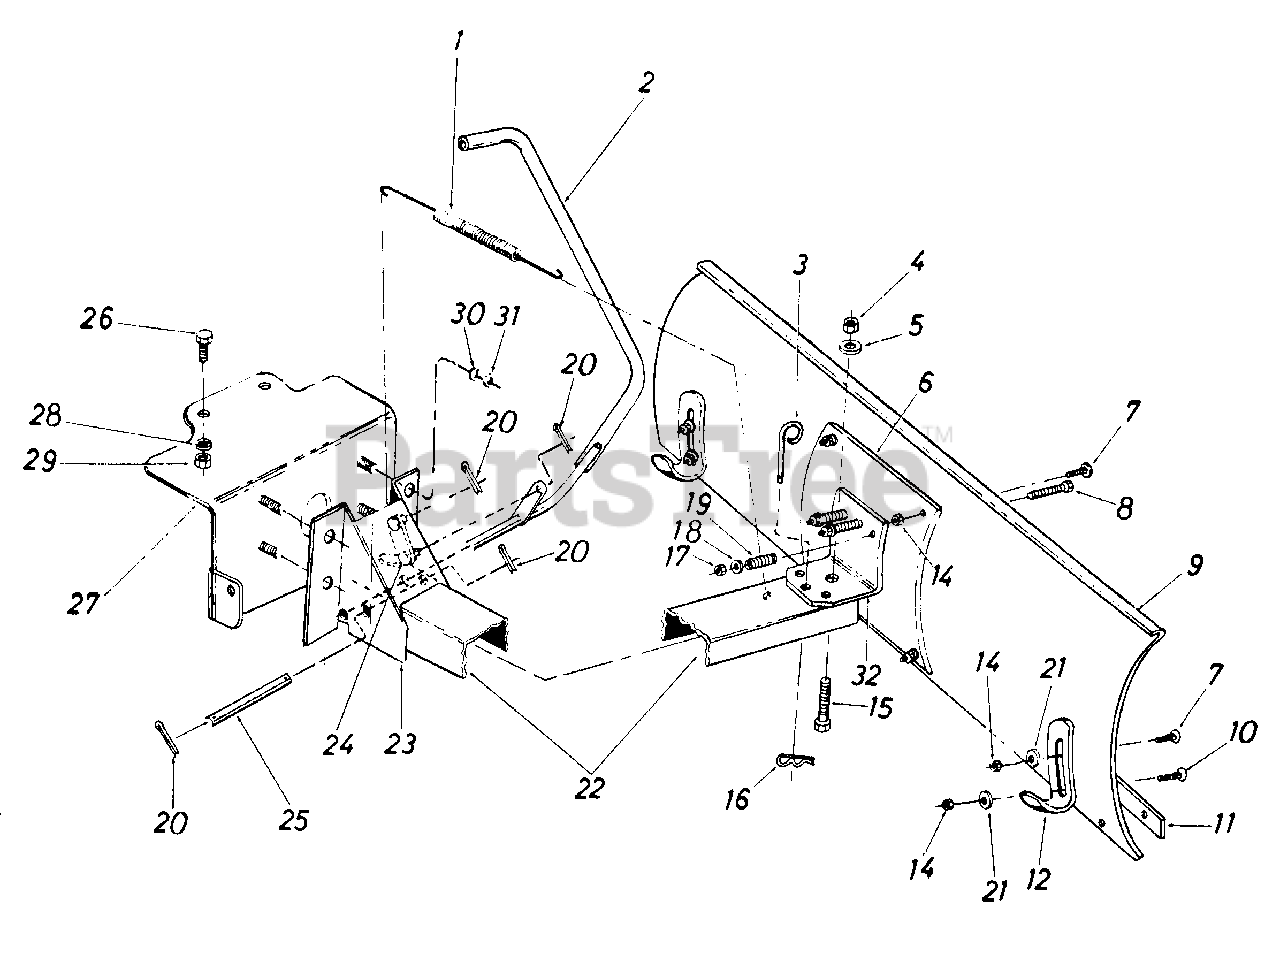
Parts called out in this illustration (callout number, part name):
1	Extension Spring
2	Lift Handle Ass'y.
3	Pivot Lock Pin
4	Hex Cent. L.-Nut 1/2-13 Thd.
5	Fl.-Wash. 17/32 I.D. x 1.25" Lg.
6	Reinforcement Plate
7	Carriage Bolt 5/16-18 x .75" Lg.*
8	Hex Scr. 3/8-16 x 3.75' Lg. Grade 5
9	42" Blade
10	Carriage Bolt 5/16-18 x 1.00" Lg.*
11	42" Wear Plate
12	Shoe Skid
14	Hex Cent. L.-Nut 5/16-18 Thd.*
15	Hex Scr. 1/2'-13 x 1.25" Lg.*
16	Hair Pin Cotter
17	Hex Cent. L.-Nut 3/8-16 Thd.
18	Fl. Wash. 3/8" I.D.
19	Compression Spring
20	Cotter Pin 1/8" Dia. x 1.00" Lg.*
21	Fl.-Wash. 5/16" I.D.
22	Push Bar Channel
23	Pivot Support Bracket
24	Lift Link
25	Channel Pivot Shaft
26	Hex Scr. 3/8-16 x 1.00" Lg. Grade 5
27	Support Bracket Ass'y.
28	L.-Wash. 3/8 I.D. *
29	Hex Nut 3/8-1 Thd.*
30	L.-Wash. 3/8" I.D.*
31	Hex Jam Nut 3/8-16 Thd.
32	Support Bracket
